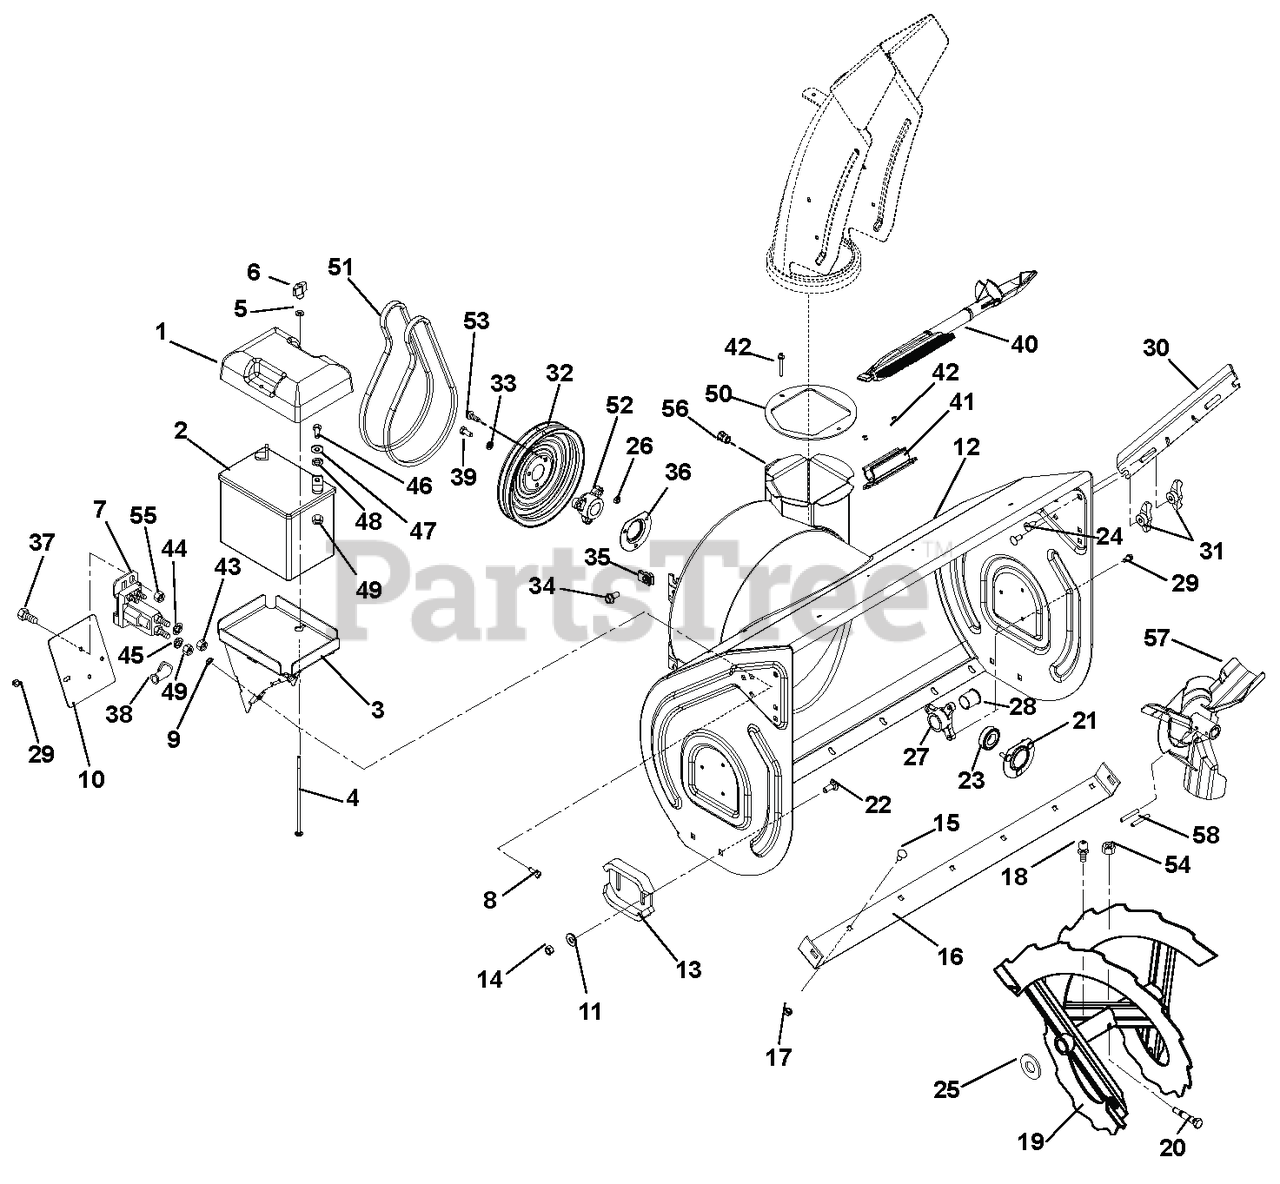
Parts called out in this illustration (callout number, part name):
1	COVER, BATTERY
3	TRAY, BATTERY-W/CLIPS
4	@BLT-RDHDSQNK .25-20X7.00 G2YZ
5	@WSHR-FL-STL.281X.62X.065 YWZC
6	KNOB, WING - .25-20 UNC
7	SOLENOID
8	BLT-HEX .25-20X.75 HWH YZ GR5
9	NUT-RTNR .25-20X.56
10	COVER, SOLENOID
11	@WSHR-FL-STL.438X1.00X.083 YWZ
12	BLOWER HOUSING W/DECAL 28"
12	BLOWER HOUSING W/DECAL 32"
12	BLOWER HOUSING W/DECAL 32" BAT
12	BLOWER HOUSING W/DECAL 36"
13	RUNNER, SKID SHOE
14	@NUT-LK-CTR .38-16 YWZC
15	BOLT, MODIFIED HEAD CARRIAGE
16	BLADE, SCRAPER-28"
16	BLADE, SCRAPER-32"
16	BLADE, SCRAPER-36"
17	@NUT-LK-TOP-FLG .31-18 YWZC
18	ZERK,FITTING .25X.125 DRIVE IN
19	RAKE, LH-28"(1 ID X 15.75 OD)
19	RAKE, RH-28"(1 ID X 15.75 OD)
19	RAKE, LH-32"(1 ID X 15.75 OD)
19	RAKE, RH-32"(1 ID X 15.75 OD)
19	RAKE, LH-36" (1 ID X 15.75 OD)
19	RAKE, RH-36"(1 ID X 15.75 OD)
20	SHEAR BOLT SERVICE ASSEMBLY
21	BEARING FLANGE
22	@BLT-RDHDSHSQNK.38-16X1.0 G5YZ
23	BRG-BALL .876X1.75X.50 RSTFP
24	@BLT-RHDSSQNK .31-18X.75 G5YZ
25	WSHR-FL-STL 1.010X1.505X.062YZ
26	@NUT-LK-CTR .25-20 YWZC
27	BUSHING, RAKE SHAFT 1"
28	BSHG-FLG SPLIT NYLINER 1.0" HP
29	SCR-TAP .25-20X.50 HWH TR YWZ
30	CUTTER, DRIFT
31	KNOB,WING .31-18 UNC NYL/TALC
32	PULLEY, SPIN FORM DUAL GROOVE
33	WSHR-LK .312X.097 HVY YWZC
34	BLT-SERHFWH .38-16X.75 YWZC
35	NUT-RTNR .375-16X.37
36	BEARING FLANGE
37	@BLT-HEX .25-20X.50 GR5 YWZC
38	BOOT, EYELET TERMINAL
39	BLT-HEX .31-24X.75 YWZC GR5
40	DEVICE, SNOW CLEAN OUT W/BRUSH
41	MOUNT, SNOW CLEAN OUT
42	RVT-POP .187 YZ
43	NUT-JAM .31-24 YWZC
44	WSHR-LOCK INT .31 YWZC
45	@WSHR-LK-EXT.262X.502X.026YWZC
46	@BLT-HEX .25-20X.75 GR5 YWZC
47	WSHR-FL-STL .265X.50X.087YWZC
48	@WSHR-LK .25X.062 REG YWZC
49	@NUT-HEX .25-20 YWZC
50	BAFFLE, DISCHARGE NECK
51	V-BELT, HA-RAW EDGE (SET)
52	PULLEY HUB, D-BORE .87 PRO
53	@SCR-TAP .31-18X.50 HWH TR YWZ
54	@NUT-LK-CTR .31-18 YWZC
55	@NUT-LK-CTR .25-20 YWZC
56	NUT, THREADED INSERT .38-16
57	IMPELLER, 3 BLADE-14"
58	PIN-ROLL .250X1.75
